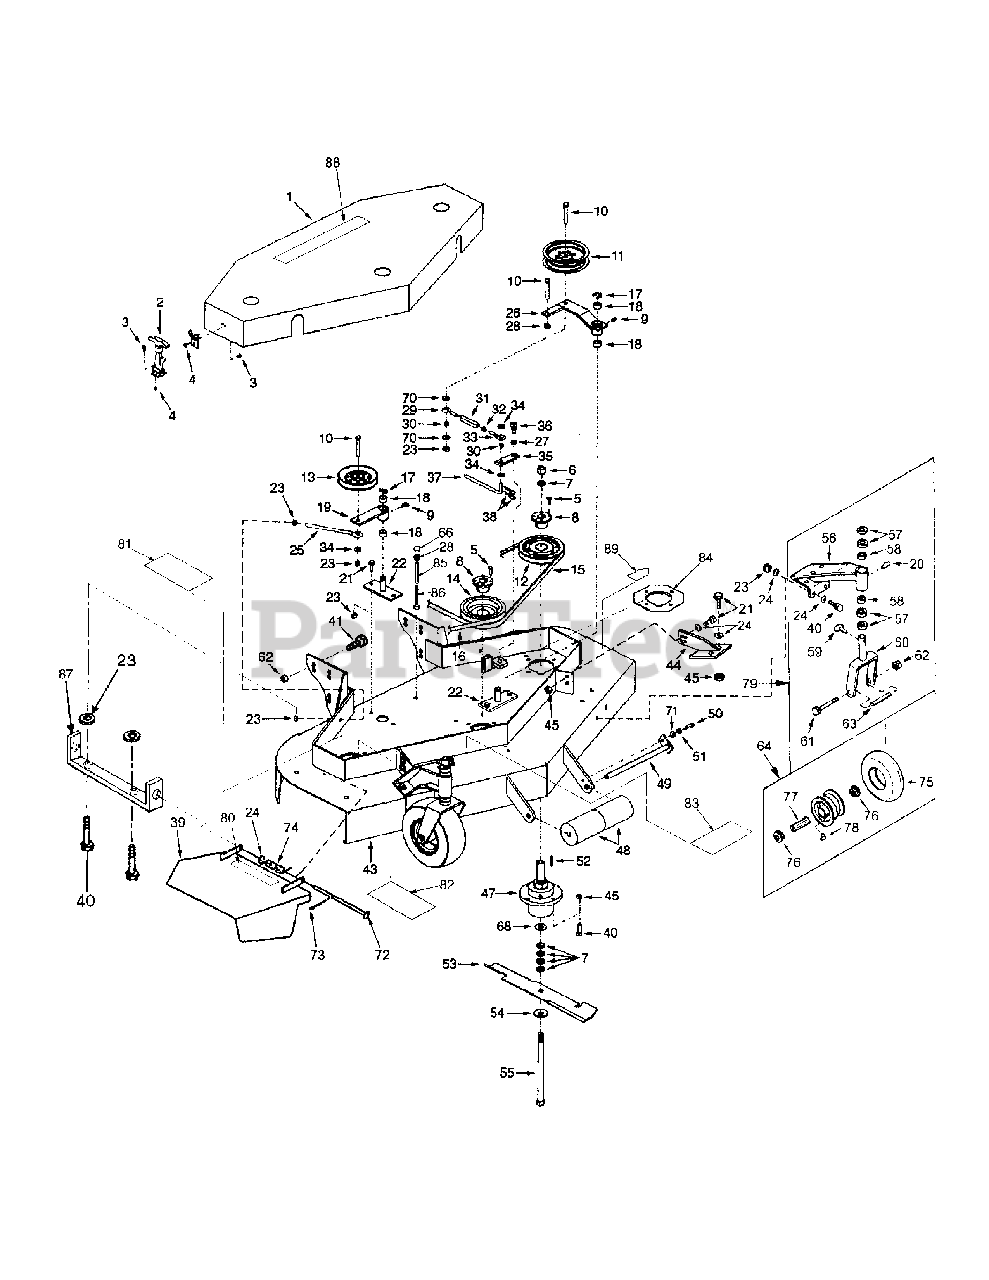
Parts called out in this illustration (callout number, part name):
1	Belt Cover
2	Latch
3	Machine Screw, #10-24 x 1/2 Rd. Hd.
4	Hex Nut, #10-24 Nylock
5	Cap Screw, 1/4-20 x 3/4 Hex Hd.
6	Hex Nut, 5/8-11
7	Blade Spacer
8	Bushing, Pulley
9	Grease Fitting, 1/4-28, 90°
10	Cap Screw, 3/8-16 x 2-1/2 Hex Hd.
11	Idler, Deck Take-Up
12	Pulley, Single Belt
13	Pulley, Idler
14	Pulley, Dual Belt
15	Belt, BK90
16	Belt, BK54
17	E-Ring, External
18	Sintered Bushing
19	Pivot Arm, Deck Idler Pulley
20	Grease Fitting, 1/4-28, Straight
21	Cap Screw, 3/8-16 x 1 Hex Hd.
22	Idler Pivot
23	Hex Nut, 3/8-16 Nylock
24	Flat Washer, 3/8 Small O.D.
25	Rod, Idler Tensioner
26	Pivot Arm, Deck Take-Up Idler Pulley
27	Shim Washer, 1/2 x 3/4 x 1/16
28	Hex Nut, 3/8-16
29	Eyebolt, L.H.
30	Sleeve
31	Turnbuckle
32	Hex Nut, 5/16-18
33	Eyebolt, R.H.
34	Flat Washer, 3/8 Large O.D.
35	Clutch Link
36	Shoulder Bolt
37	Rod, Blade Clutch
38	Clip, Hairpin, 3/8-7/16
39	Discharge Chute
40	Cap Screw, 3/8-16 x 1-1/4 Hex Hd.
41	Cap Screw, 1/2-13 x 1-1/4 Hex Hd.
42	Lock Washer, 1/2 Heavy
43	Deck, 52" Walk-Behind
44	Caster Brace
45	Hex Nut, 3/8-16 Stover
46	Belt Guide
47	Spindle Assembly
48	Roller, Anti-Scalping
49	Axle
50	Cap Screw, 5/16-18 x 3/4 Hex Hd.
51	Lock Washer, 5/16
52	Key, 1/4 x 1/4 x 2
53	Blade, Rotary 18
54	Flat Washer, 5/8
55	Cap Screw, 5/8-11 x 9-1/2 Hex Hd.
56	Caster Bracket
57	Caster Spacer
58	Bushing, Caster Bracket
59	Lynch Pin
60	Caster Yoke
61	Cap Screw, 1/2-13 x 5-1/2 Hex Hd.
62	Hex Nut, 1/2-13 Nylock
63	Sleeve, Caster Wheel Bearing
64	Tire and Wheel Assembly, 9 x 3.50 - 4
65	Cap Screw, 3/8-16 x 5 Hex Hd.
66	Protective Cap
68	Flat Washer, 1-1/2 x 5/8 x .055
69	Flat Washer, 3/8 Heavy
70	Flat Washer, 5/16 USS
71	Flat Washer, 5/16
72	Deflector Pin Ass'y
73	Cotter Pin 1/8" x 1"
74	Torsion Spring
75	Tire, Caster Wheel
76	Bearing Retainer, Caster Wheel
77	Roller Bearing, Caster Wheel
78	Grease Fitting
79	Caster Assembly
80	Decal, "Width Cut"
81	Decal, Rotating Blade
82	Decal, Warning Safety
83	Decal, Warning Shield
84	Plate, Spindle Backing
85	Spacer, Belt Guard
86	Bolt, Carriage 3/8-16 x 1
87	Bracket, Deflector
88	Label, Cutter Deck
89	Decal, Danger
